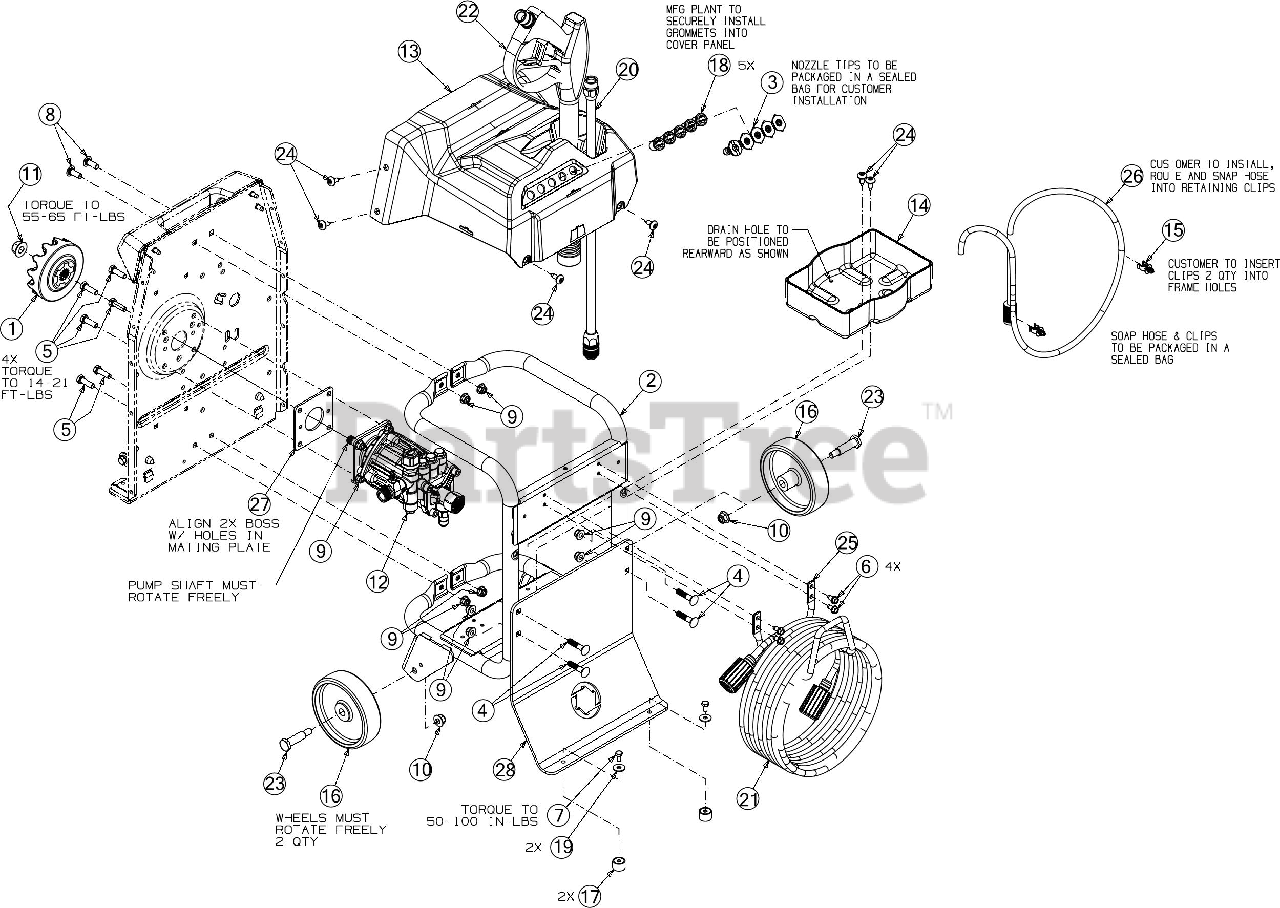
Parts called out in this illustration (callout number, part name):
1	DOG CLUTCH BUMPER
1	DOG CLUTCH
1	DOG CLUTCH ASSEMBLY
2	FRAME ASSEMBLY
3	NOZZLE FITTING ASSEMBLY
4	CARRIAGE BOLT 5/16-18 x 1.50
5	SCREW 5/16-18 x 1.0 GR5
6	SCREW 1/4-20 X.500
7	SCREW M6-1 x 12
8	BOLT 5/16-18X .875 GR1
9	FLANGE LOCK NUT 5/16-18
12	PRESSURE WASHER PUMP
13	POWER WASH COVER
16	PLASTIC WHEEL 5X1.38
19	SPRING WASHER BELL
20	EXTENSION TUBE
21	ATTACHMENT HOSE .25 x 40FT
22	CONTROL HANDLE
23	SHOULDER SCREW
24	TORX SHOULDER SCREW 1/4-20
25	HOSE HANGER ROD
26	INLET SOAP TUBE
27	PUMP PLATE
